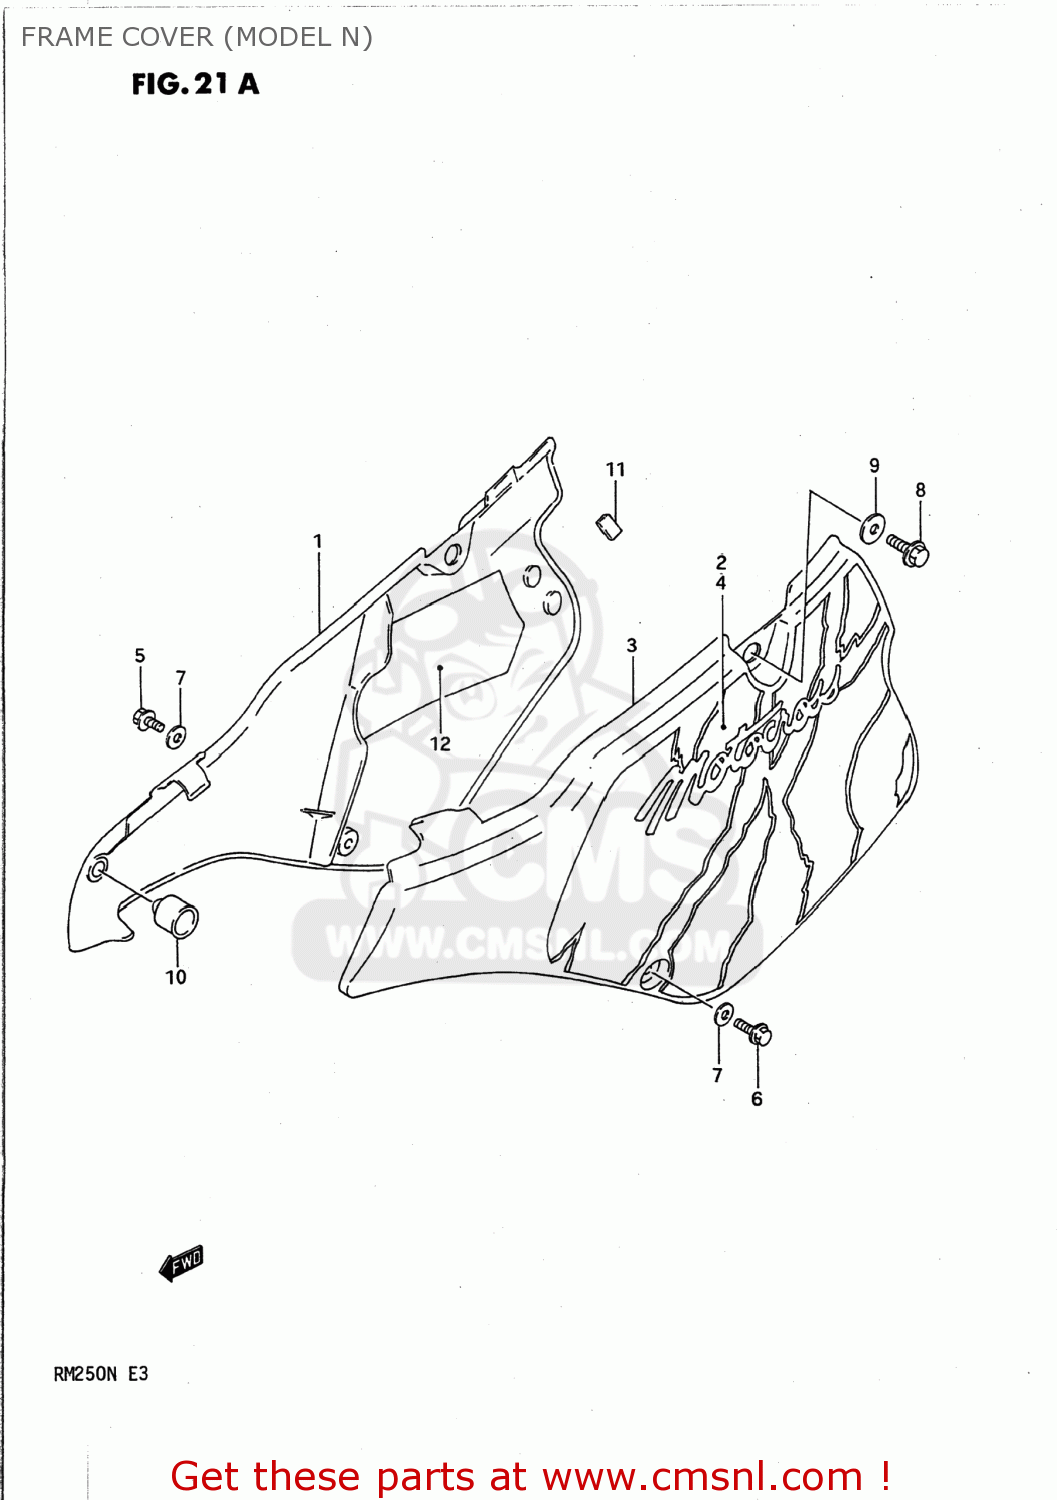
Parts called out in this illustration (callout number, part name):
1	COVER,FRAME,RIGHT
2	EMBLEM,FRAME COVER,RIGHT
3	COVER,FRAME,L(WHITE)
4	EMBLEM,FRAME COVER,LEFT
5	BOLT
6	BOLT
7	GASKET(6.5X20X1.5) (NAS)
8	BOLT
9	WASHER
10	CUSHION
11	CUSHION,FRAME COVER,REAR
12	SHIELD,FRAME COVER,RIGHT
